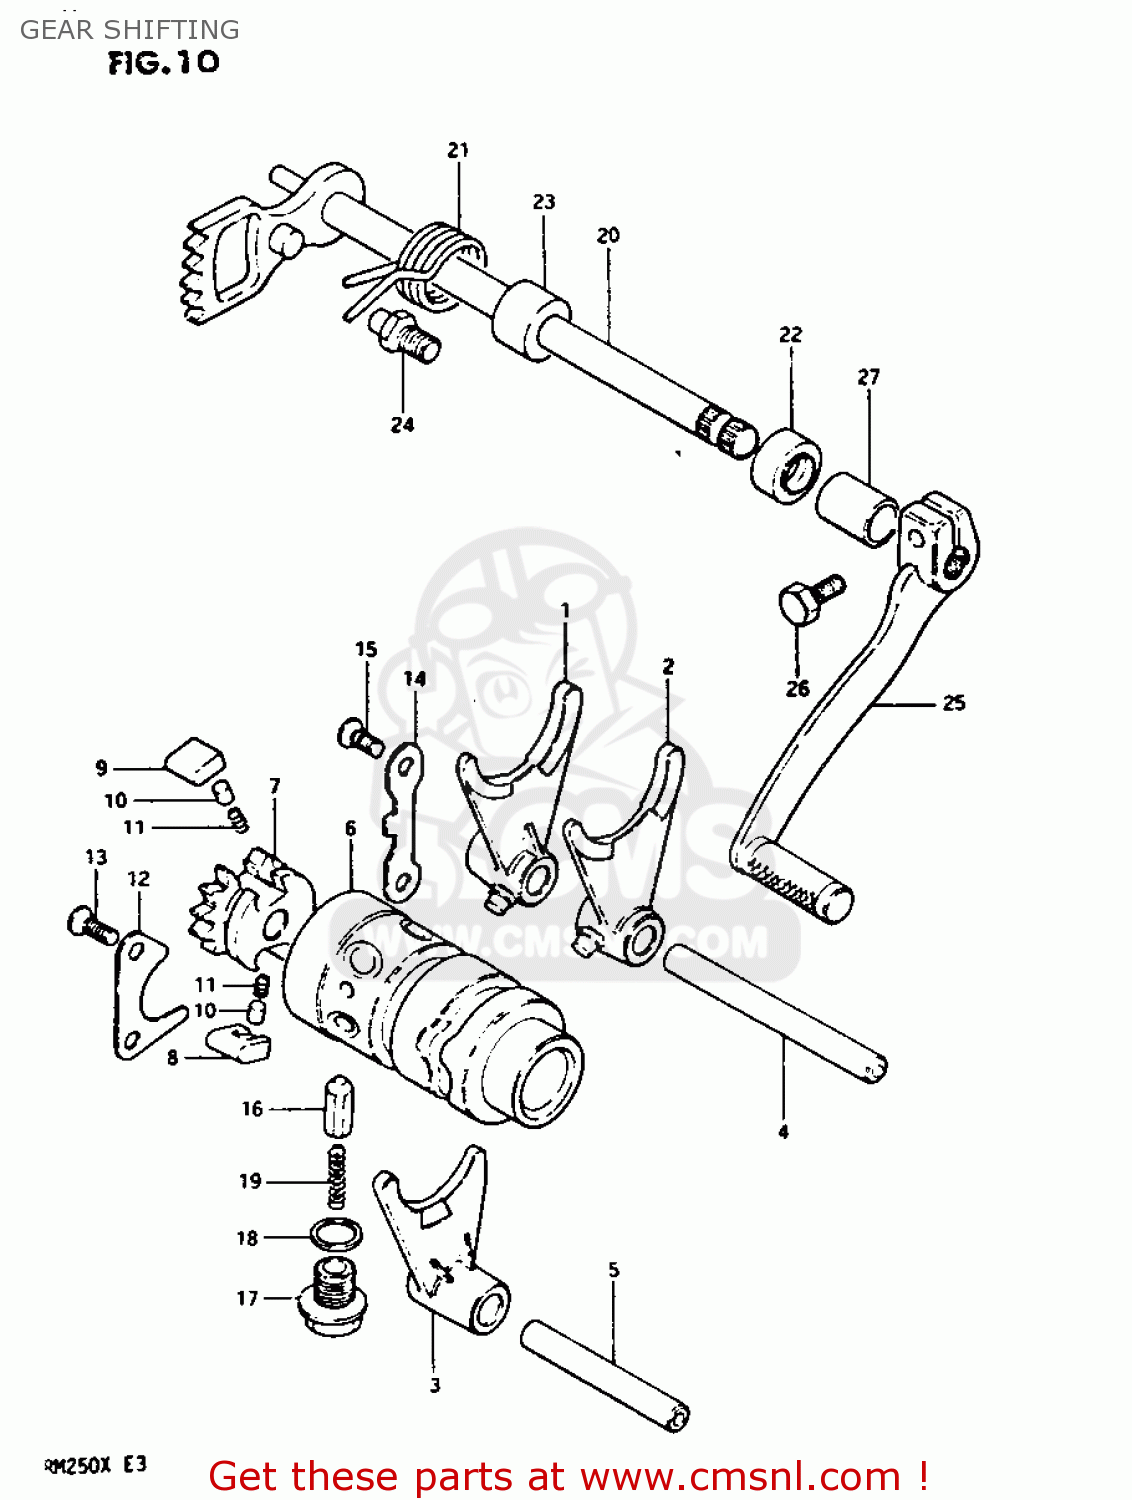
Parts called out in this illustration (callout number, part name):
1	FORK,GEAR SHIFT NO.1
2	FORK,GEAR SHIFT NO.2
3	FORK,GEAR SHIFT NO.3
4	SHAFT,GEAR SHIFT FORK
5	SHAFT,GEAR SHIFT FORK
6	CAM,GEAR SHIFT
7	GEAR,GEARSHIFT CAM DRIVE
8	PAWL,GEAR SHIFT NO.1
9	PAWL,GEAR SHIFT NO.2
10	PIN(5X8)
11	SPRING
12	LIFTER,GEAR SHIFT PAWL
13	SCREW
14	STOPPER,GEAR SHIFT POLE
15	SCREW
16	STOPPER,GEAR SHIFTING
17	BOLT,GEAR SHAFT CAM STOPPER
18	GASKET(14X19.2X2) (NAS)
19	SPRING
20	SHAFT,GEAR SHIFT
21	SPRING
22	OIL SEAL
23	SPACER(12X20X15.3)
24	STOPPER,GEAR SHIFT CAM
25	LEVER,GEAR SHIFT
26	BOLT
27	CUSHION
